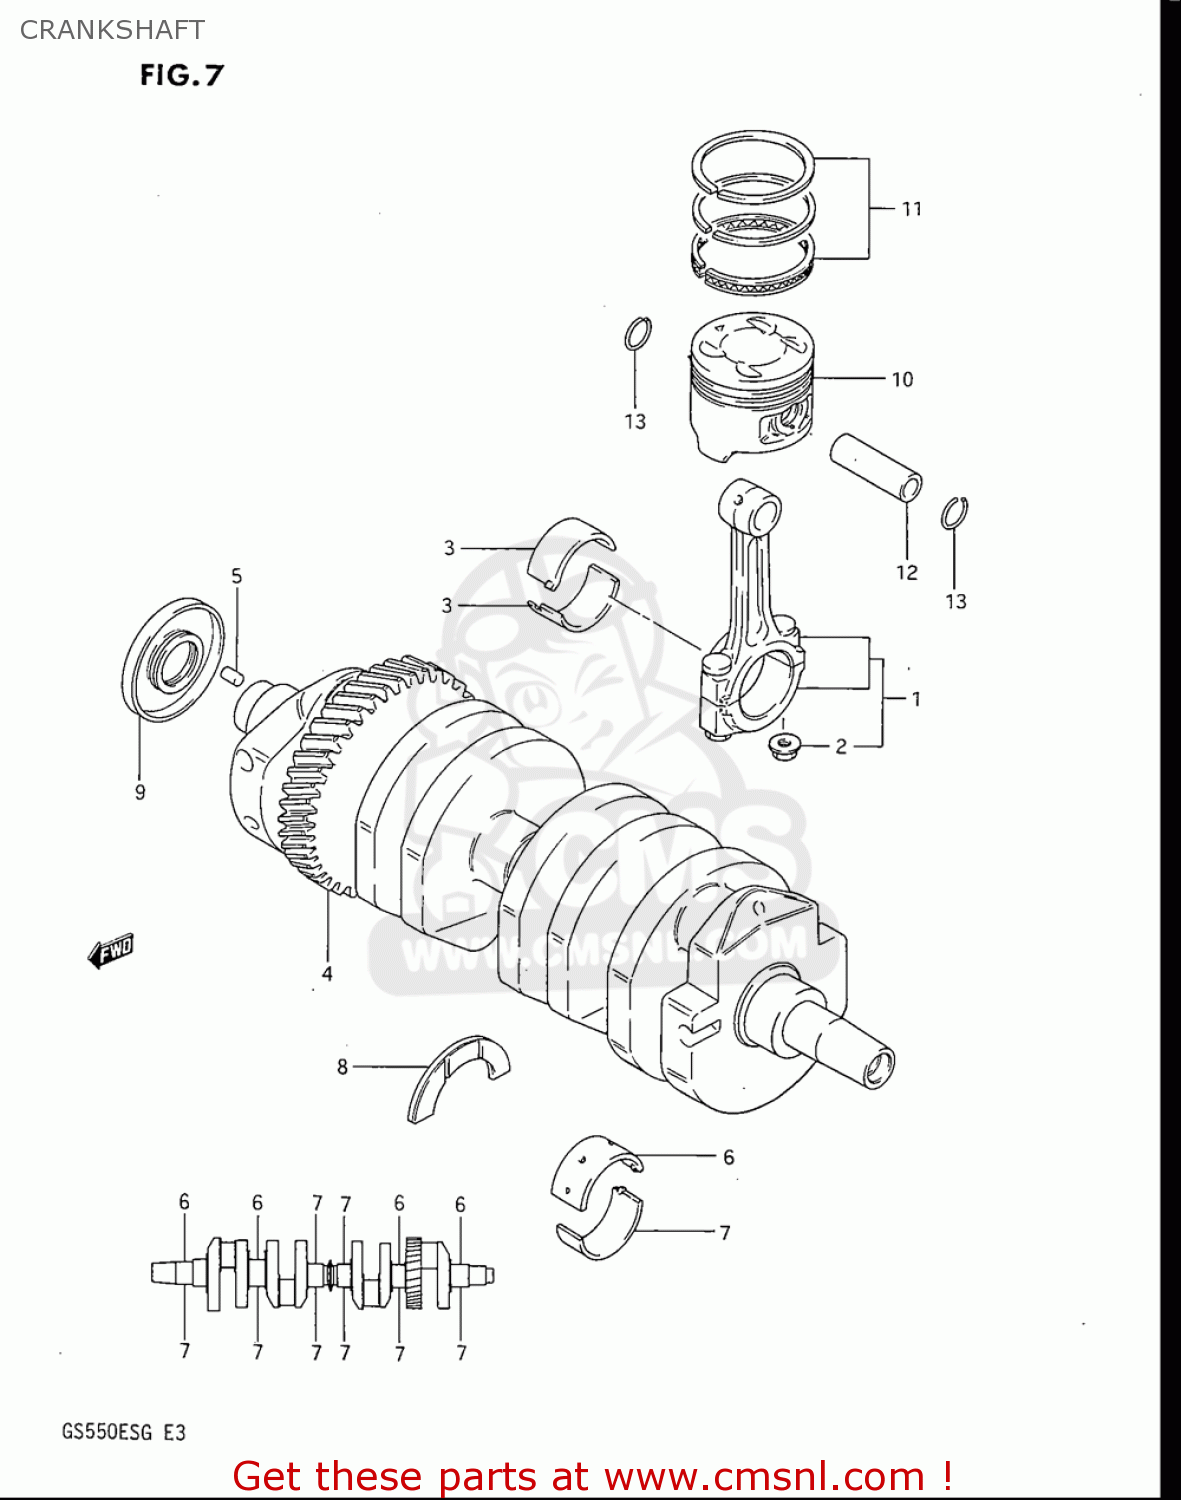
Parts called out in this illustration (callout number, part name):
2	NUT
3	METAL,CRANK PIN
5	PIN
6	METAL,CRANKSHAFT
7	METAL,CRANKSHAFT
8	PLATE,CRANK THRUST
9	OIL SEAL
10	PISTON SET
11	RING SET,PISTON
12	PIN,PISTON
13	RING,SNAP 16MM
